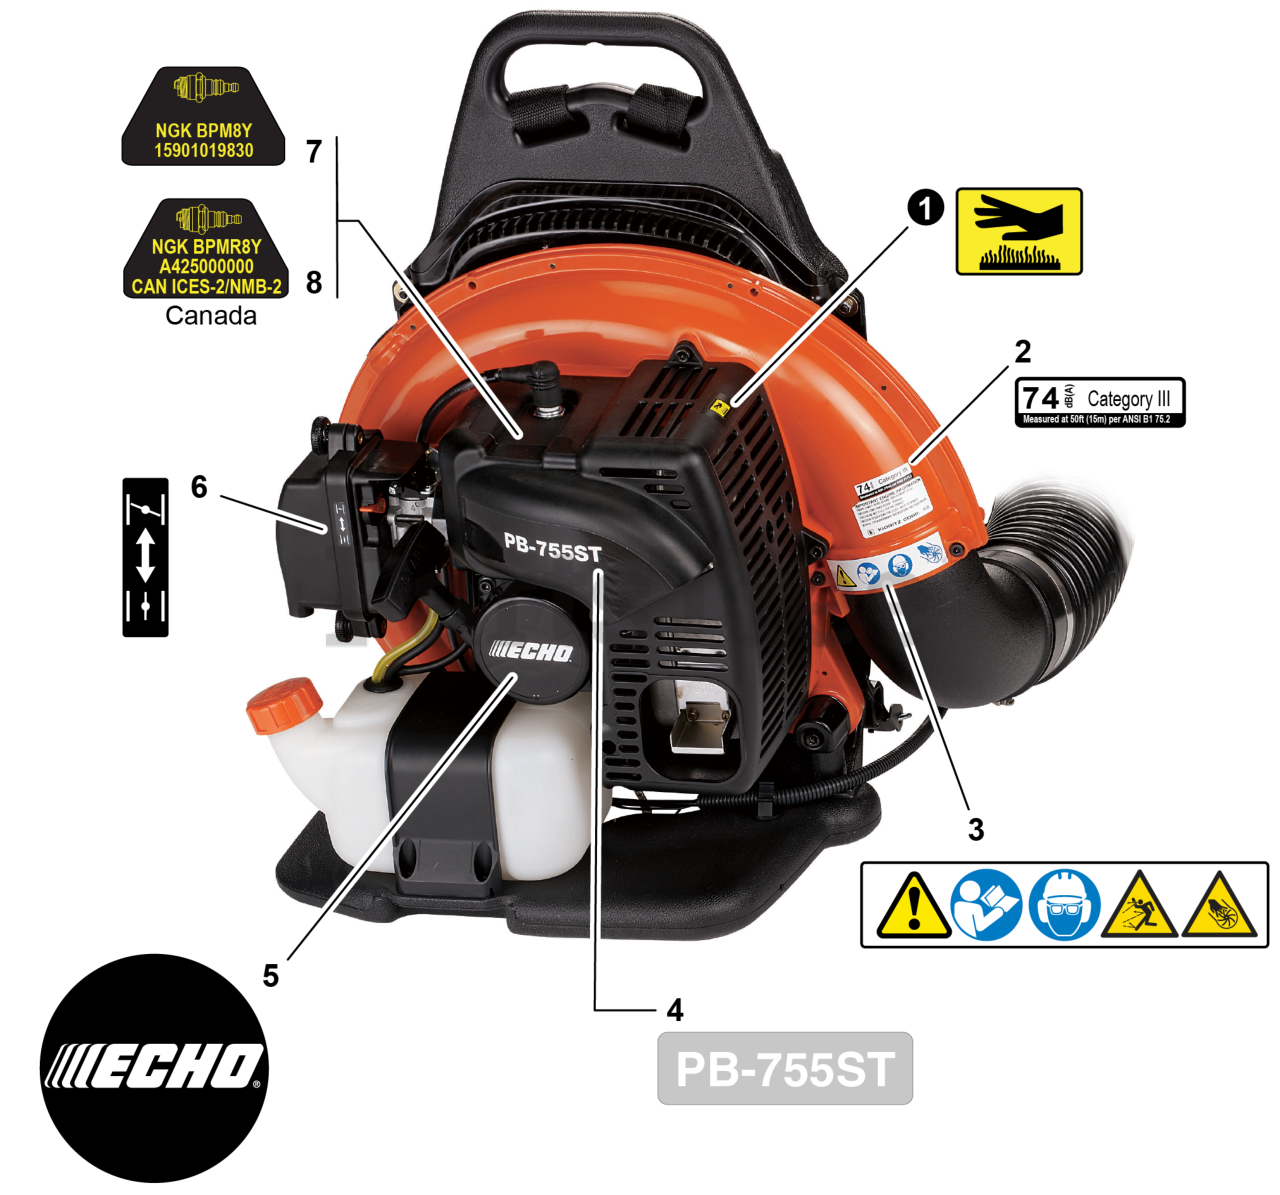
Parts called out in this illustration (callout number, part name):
1	LABEL - CAUTION - HOT
2	LABEL - NOISE - 74DB(A) CAT. III
3	LABEL - CAUTION - ISO
4	LABEL, MODEL PB-755ST
5	LABEL - STARTER - ECHO
6	LABEL - CHOKE
7	LABEL - SPARK PLUG - BPM8Y
8	LABEL - SPARK PLUG - BPMR8Y
